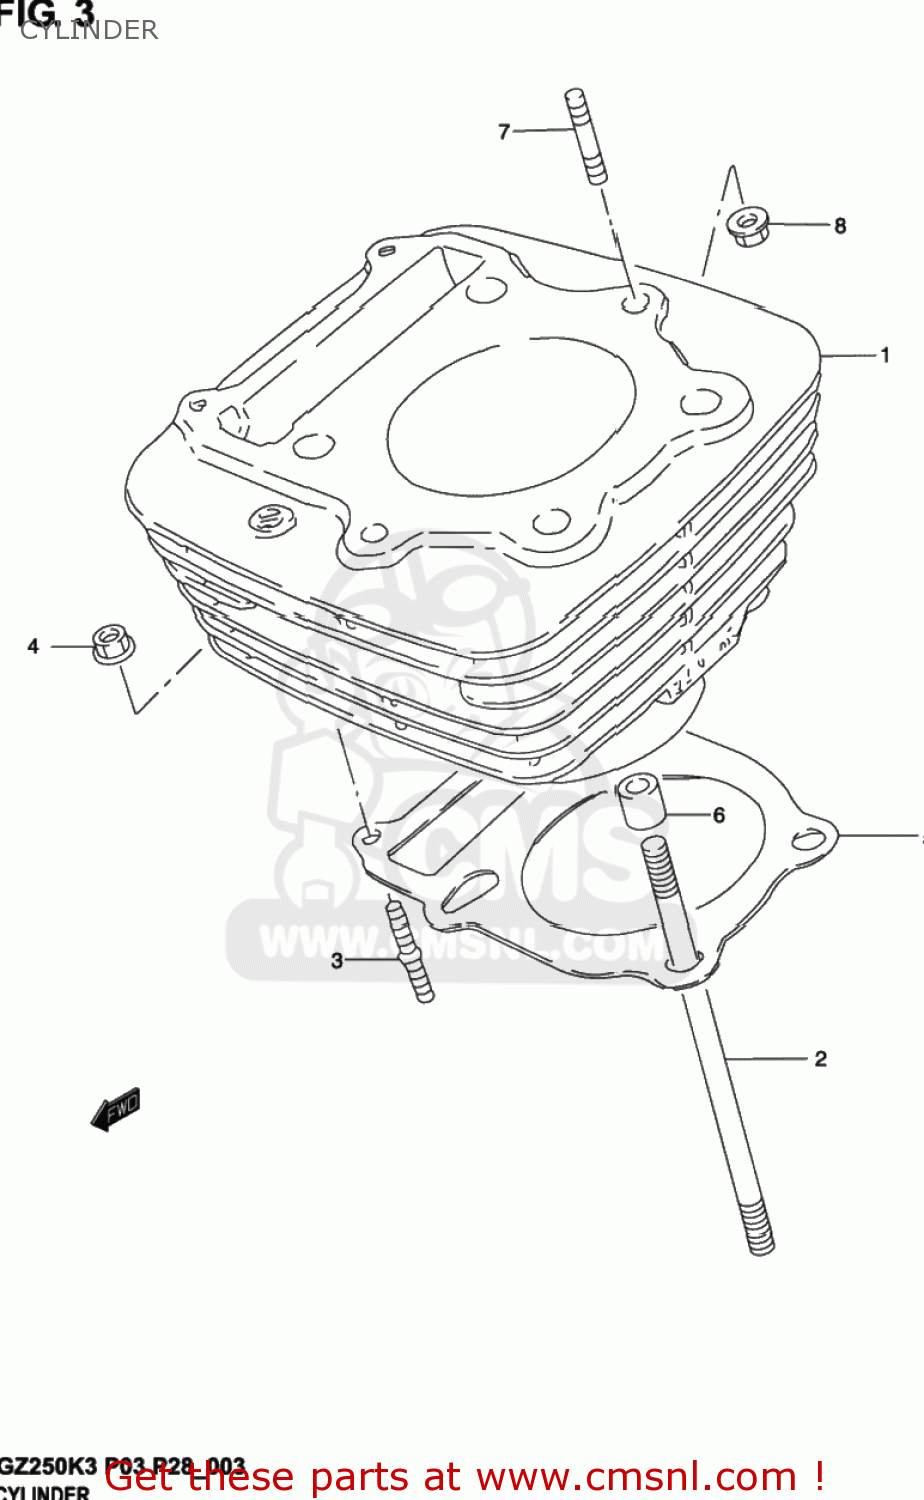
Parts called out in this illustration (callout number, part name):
1	CYLINDER
2	BOLT,STUD
3	STUD 6X20
4	NUT
5	GASKET,CYLINDER (NAS)
6	PIN
7	BOLT,STUD
8	NUT
